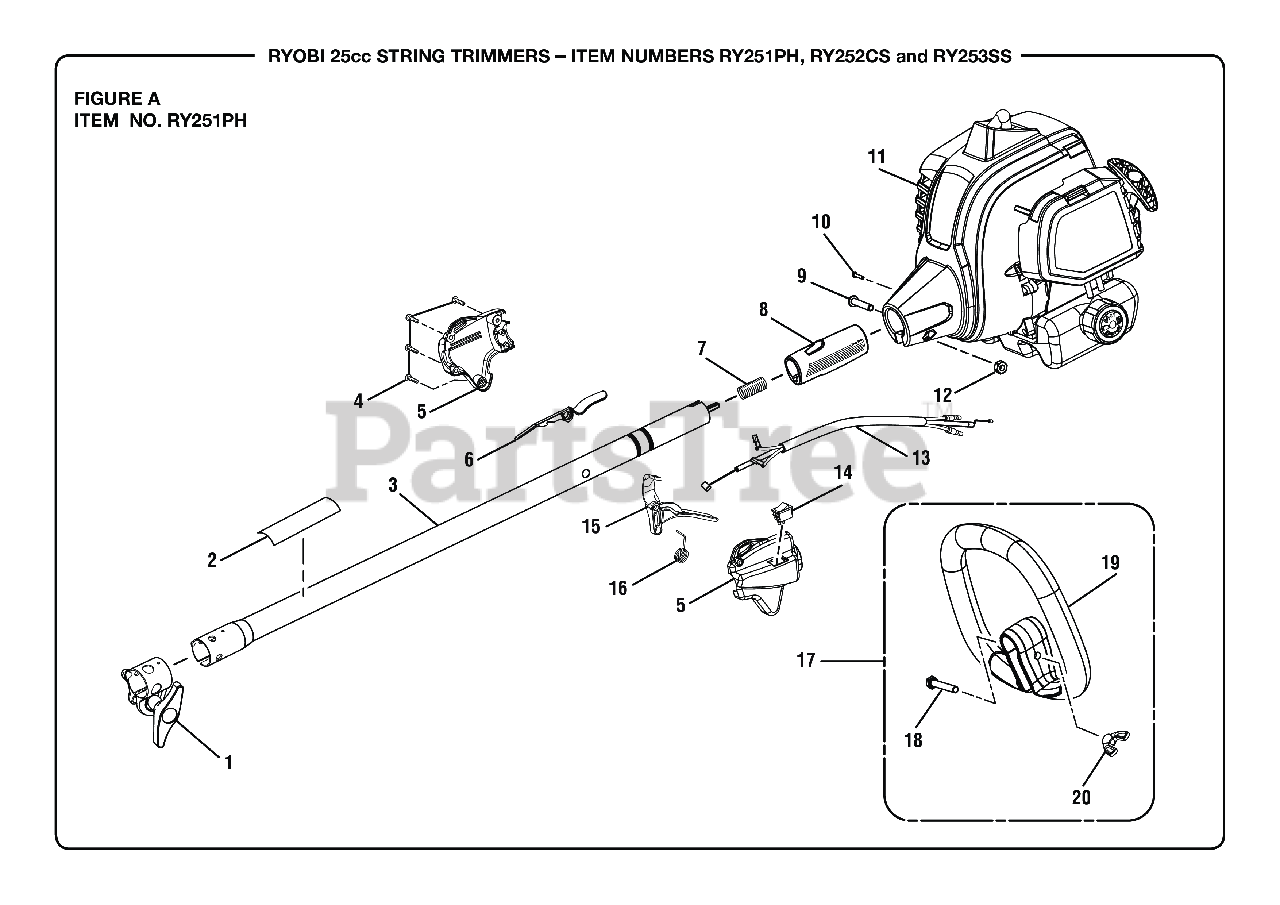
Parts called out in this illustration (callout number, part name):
1	Boom Clamp Assembly
2	Warning Icon Label
3	Upper Boom Assembly
4	Screw (M4 x 20 mm, T20 Torx Pan Hd. S.T.)
5	Control Handle Assembly (Inc. Key No. 6)
6	Trigger Lock
7	COMPRESSION SPRING
8	Rear Handle Grip
9	Screw (M6 x 30 mm, T27 Torx Button Hd.)
10	Screw (M4 x 8 mm, T25 Torx Pan Hd. T.F.)
11	Powerhead Assembly w/Labels
12	Hex Nut (M6.3 x 1)
13	Throttle Cable and Wire Assembly
14	Stop Switch (Momentary Contact)
16	Torsion Spring (Throttle Trigger)
17	Auxiliary Handle Assembly
18	Screw (1/4-20 x 40 mm, Cap Hex Hd.)
19	Front Handle
20	Wing Nut (1/4-20, Plastic)
